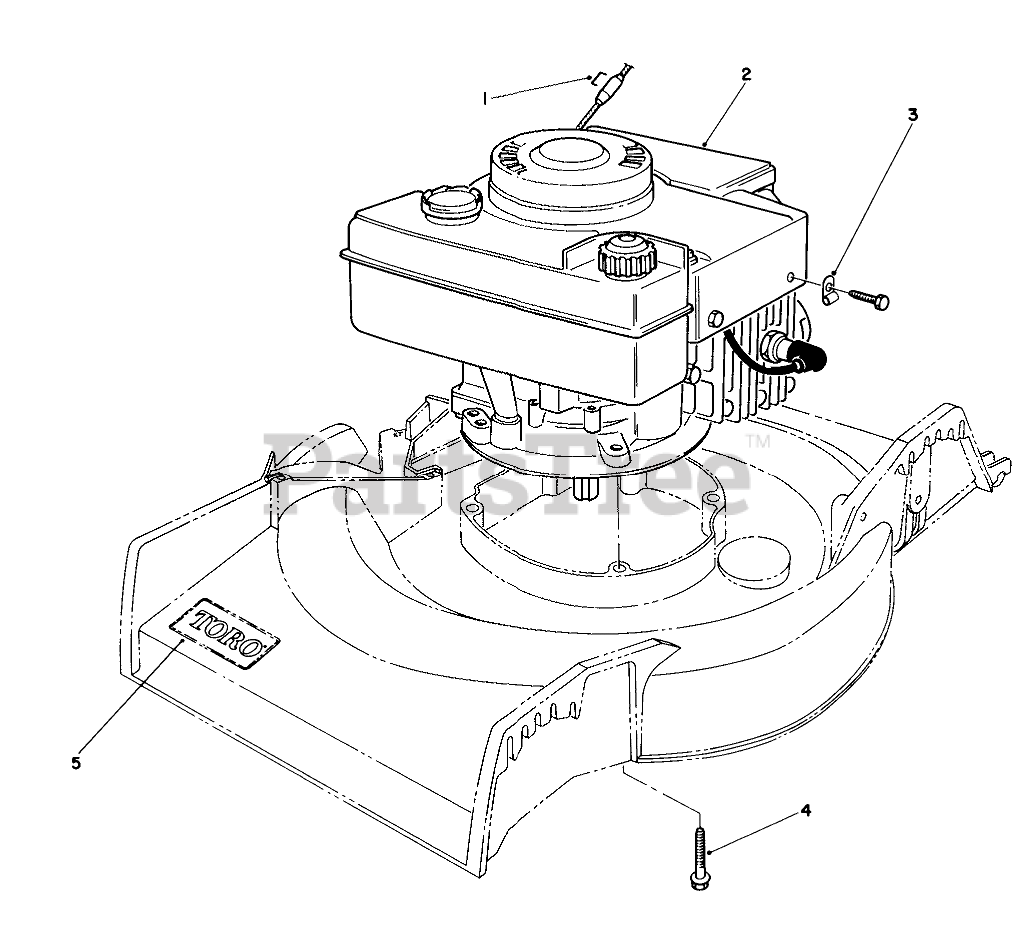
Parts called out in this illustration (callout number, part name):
1	Staple
3	CLAMP
4	3/8-16 X 2-3/4 CAPSCR
5	DECAL
